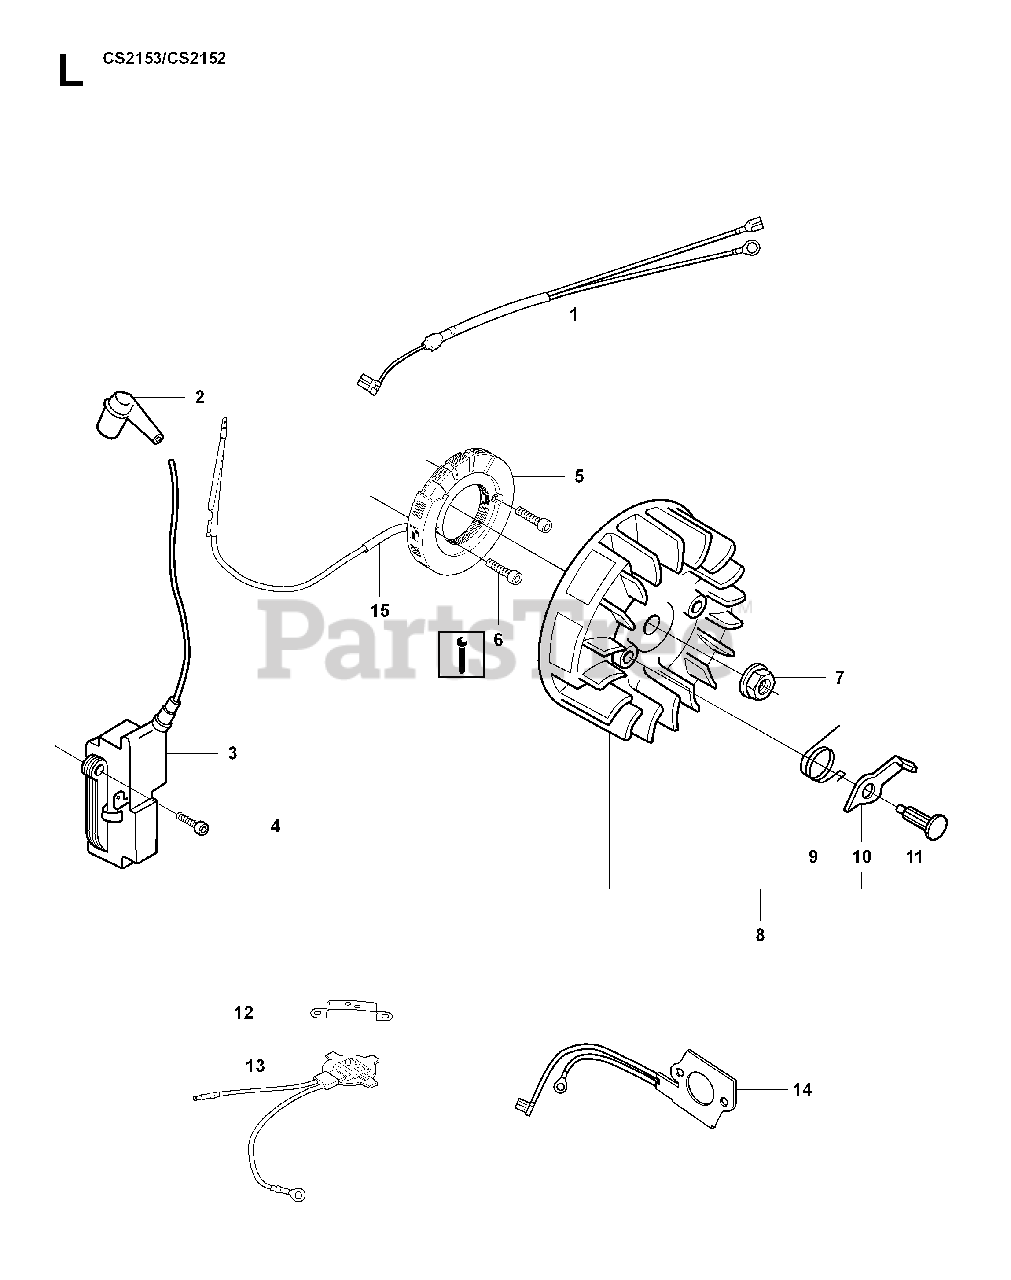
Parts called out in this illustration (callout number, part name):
1	WIRING ASSY
1	WIRING ASSEMBLY
2	SPARK PLUG CONN. KIT
3	IGNITION MODULE
3	%IGNITION MODULE
5	GENERATOR
5	GENERATOR STATOR
7	NUT W/ WASHER
8	FLYWHEEL (G)
8	FLYWHEEL
9	%SPRING, STARTER CATCH
13	THERMOSTAT ASSY
14	HEATING PLATE
15	CABLE COVER
